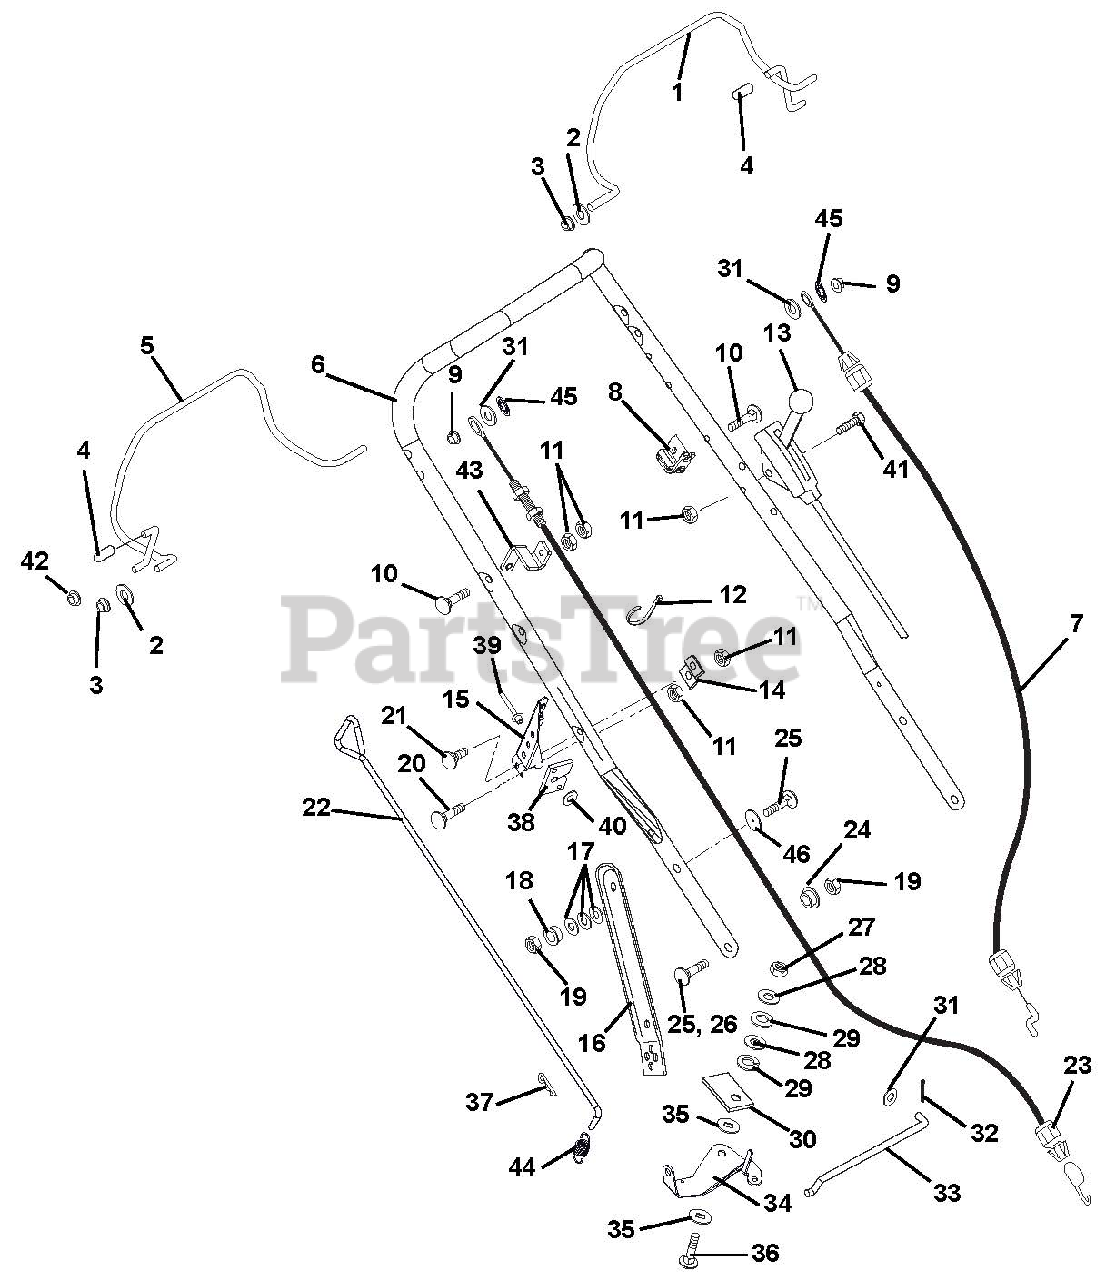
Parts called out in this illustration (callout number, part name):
1	BAIL, WBLM ENGINE
2	@WSHR-FL-STL.344X.688X.065YWZC
3	BSHG-FLG .325X.444X.440X.560
4	CAP, VINYL, .25 ID
5	BAIL, WBLM TRACTION
6	HANDLE BAR, CLASSIC LM21
7	CABLE, ENGINE - ADJUSTABLE
7	CABLE, OPC CLASSIC LM CE DOV
8	BRKT, ENGINE CABLE ANCHOR
9	PUSH NUT, .25
10	BLT-RDHDXLSQNK.25-20X1.25 G5ZC
11	@NUT-LK-CTR .25-20 YWZC
12	CABLE TIE LG 5-1/2
13	CABLE, LOCKOUT CONTROL
14	BRACE, SPEED CONTROL
15	BRKT, SPD CONTROL SLOTTED
16	LINK, HANDLEBAR ADJUSTMENT LH
16	LINK, HANDLEBAR ADJUSTMENT RH
17	WASHER, BELLEVILLE YWZC
18	BSHG-FLG .325X.500X.513X.875
19	@NUT-LK-CTR .31-18 YWZC
20	BLT-RDHDSQNK .25-20X1.38 GR5YZ
21	@BLT-RDHDSQNK .25-20X.50 G5YZ
22	SPEED CONTROL ROD
23	CABLE, WBLM TRACTION
24	BSHG, FLG .325X.499X.26X.88
25	@BLT-RDHDSQNK .31-18X1.00 G5YZ
26	@BLT-RDHDSQNK .31-18X.75 G5YZ
27	@NUT-LK-CTR .38-16 YWZC
28	@WSHR-FL-STL.406X.812X.065 YWZ
29	WSHR-LK .375X.115 HVY YWZC
30	PRESSURE FLANGE
31	@WSHR-FL-STL.281X.62X.065 YWZC
32	@PIN-CTR .06X.50 EXTPRSQCT YWZ
33	SHIFT LINK
34	CRANK, SPEED CONTROL BELL
35	FRICTION WASHER
36	@BLT-RHDSSQNK .38-16X1.25 G5YZ
37	PIN-HAIR INT .08X.18X1.18 YWZC
38	PAD, RUBBER SUPPORT
39	RVT .187X.575 DOME AL BLACK
40	@WSHR-FL-STL.219X.50X.049 YWZC
41	BLT-RDHDXLSQNK .25-20X2.0 G5YZ
42	NUT-PUSH .312 DIA. PAL
43	BRKT, TRACTION CABLE ANCHOR
44	SPRING, EXTENSION
45	RG-RTNG-EXT .250X.010
46	WSHR-FL-STL .505X.880X.072 YWZ
